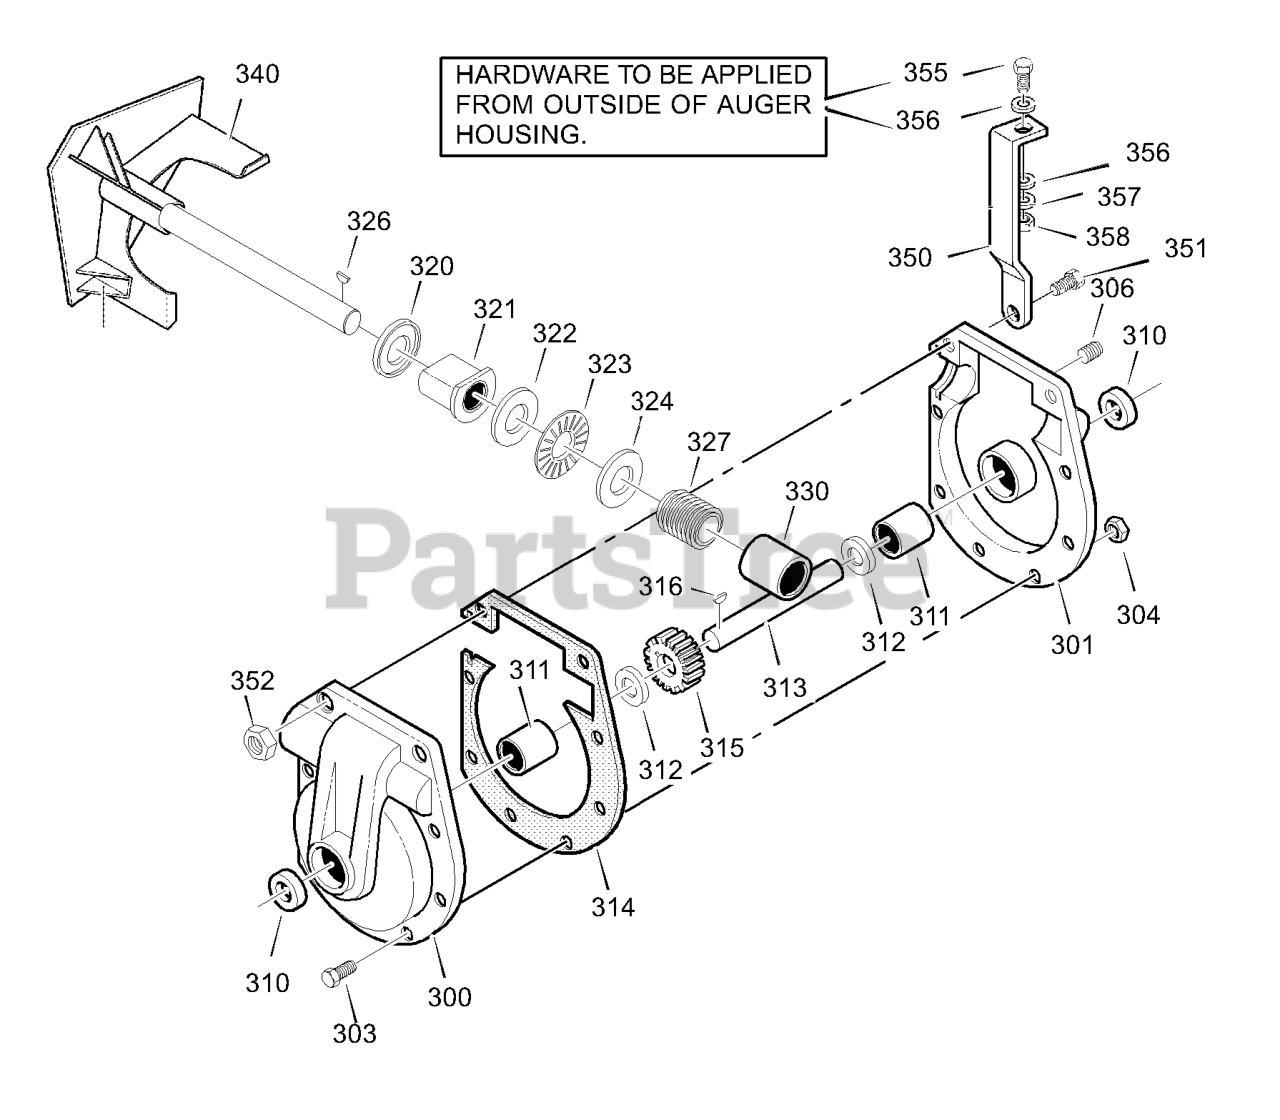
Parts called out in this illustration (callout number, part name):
300	CASE, GEAR, RH
301	CASE, GEAR, LH
303	SCREW, 5/16-24 x 1.00
304	NUT, 5/'16-24
306	PLUG, PIPE 0.25-18
310	SEAL, OIL
311	BEARING, SLEEVE
312	WASHER, FLAT
313	SHAFT, AUGER OUTPUT
314	GASKET, GEAR BOX
315	WORM GEAR
316	KEY, WOODRUFF #91
320	RING, QUAD 0.924 ID
321	BEARING, FLANGE
322	WASHER, FLAT
323	BEARING, ROLLER
324	WASHER, FLAT
330	BEARING, SLEEVE
350	BRACE, GEAR BOX
351	SCREW, 5/16-24 x 1.75
352	NUT, HEX 5/16-24
355	SCREW, 5/16-18 x 1.25
356	WASHER, FLAT
357	WASHER, SPTLK
358	NUT, REGHEX 5/16-18
